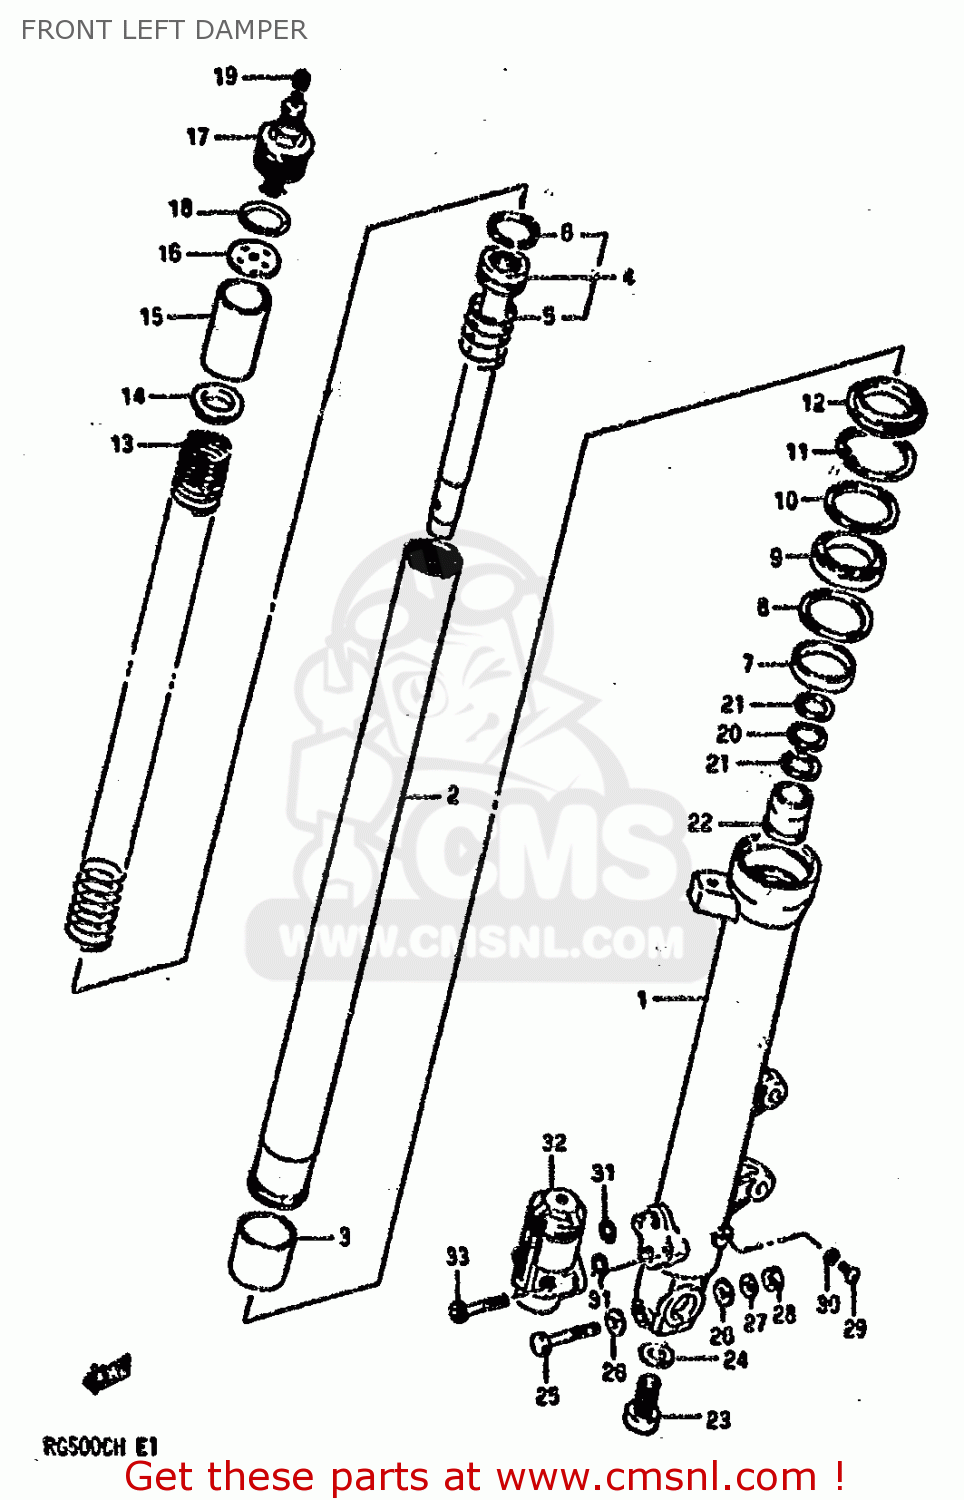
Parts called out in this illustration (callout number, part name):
1	TUBE,OUTER LH
2	TUBE,INNER
3	PISTON
4	CYLINDER
5	SPRING,REAR CUSHION
6	RING,PISTON
7	METAL,SLIDE
8	WASHER(40X50X2.3)
9	SEAL,OIL
10	WASHER,OIL SEAL
11	RING,STOPPER
12	SEAL,DUST
13	SPRING
14	GUIDE,SPRING
15	SPACER,FRONT FORK SPRING
16	WASHER
17	CAP
18	O RING
19	CAP,VALVE AIR
20	WASHER
21	SPRING,LEAF
22	PIECE,OIL LOCK
23	BOLT,CYLINDER
24	GASKET,CYLINDER (NAS)
25	BOLT 8X55
26	WASHER
27	LOCK WASHER
28	NUT ,8MM
29	SCREW
30	GASKET,DRAIN,PLUG (NAS)
31	O RING
32	PDF ASSEMBLY
33	BOLT
